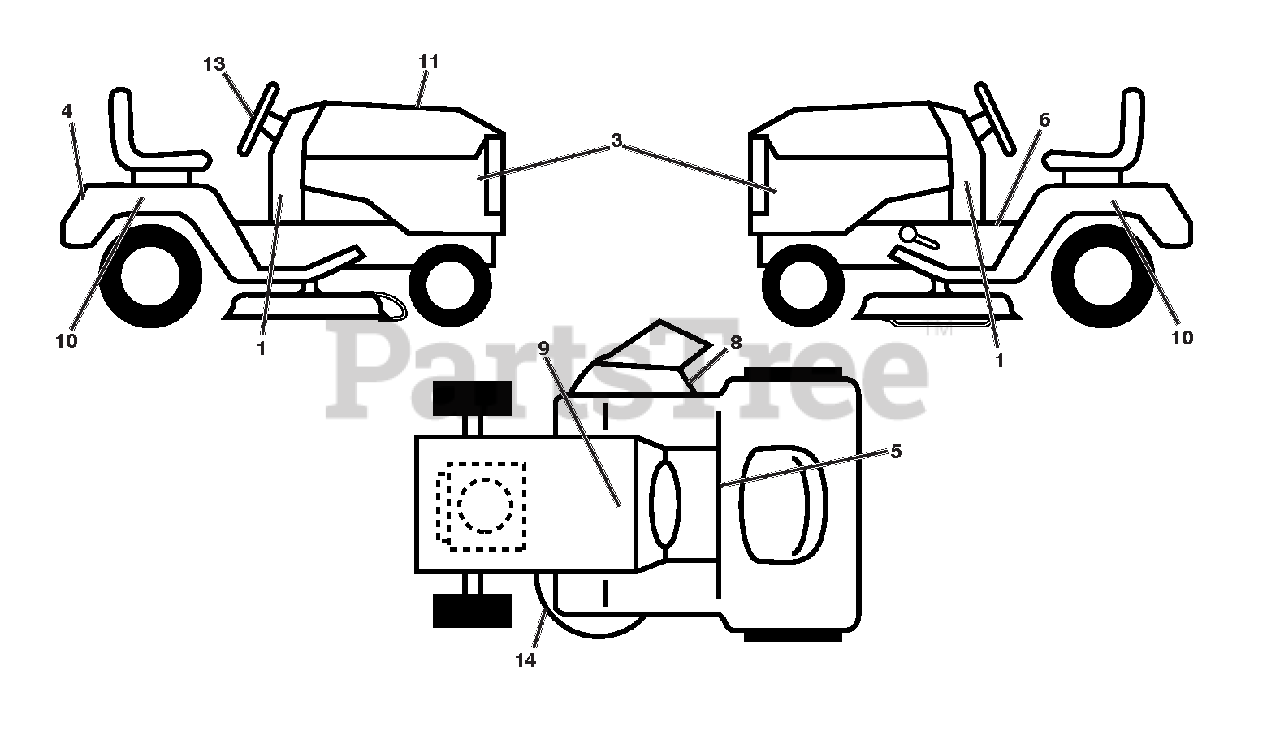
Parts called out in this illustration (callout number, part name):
1	DECAL.DASH
3	DECAL.SDPNL.PWRDBY KOHL.ARIENS
4	DECAL.FENDER.REAR.ARIENS
5	DECAL.FENDER
6	DECAL, WARNING START INST.
8	DECAL.MOWER.WARN.KEEP HAND AWY
9	DECAL.BAT.DAN/POI P/L SYM.WPN
10	DECAL.FENDER.SIDE.HYDRO.ARIENS
11	PARTS MANUAL
13	DECAL.WHEEL.STEER.ARIENS
14	DECAL.V-BELT.SCH.42/46"MEC/ELE
